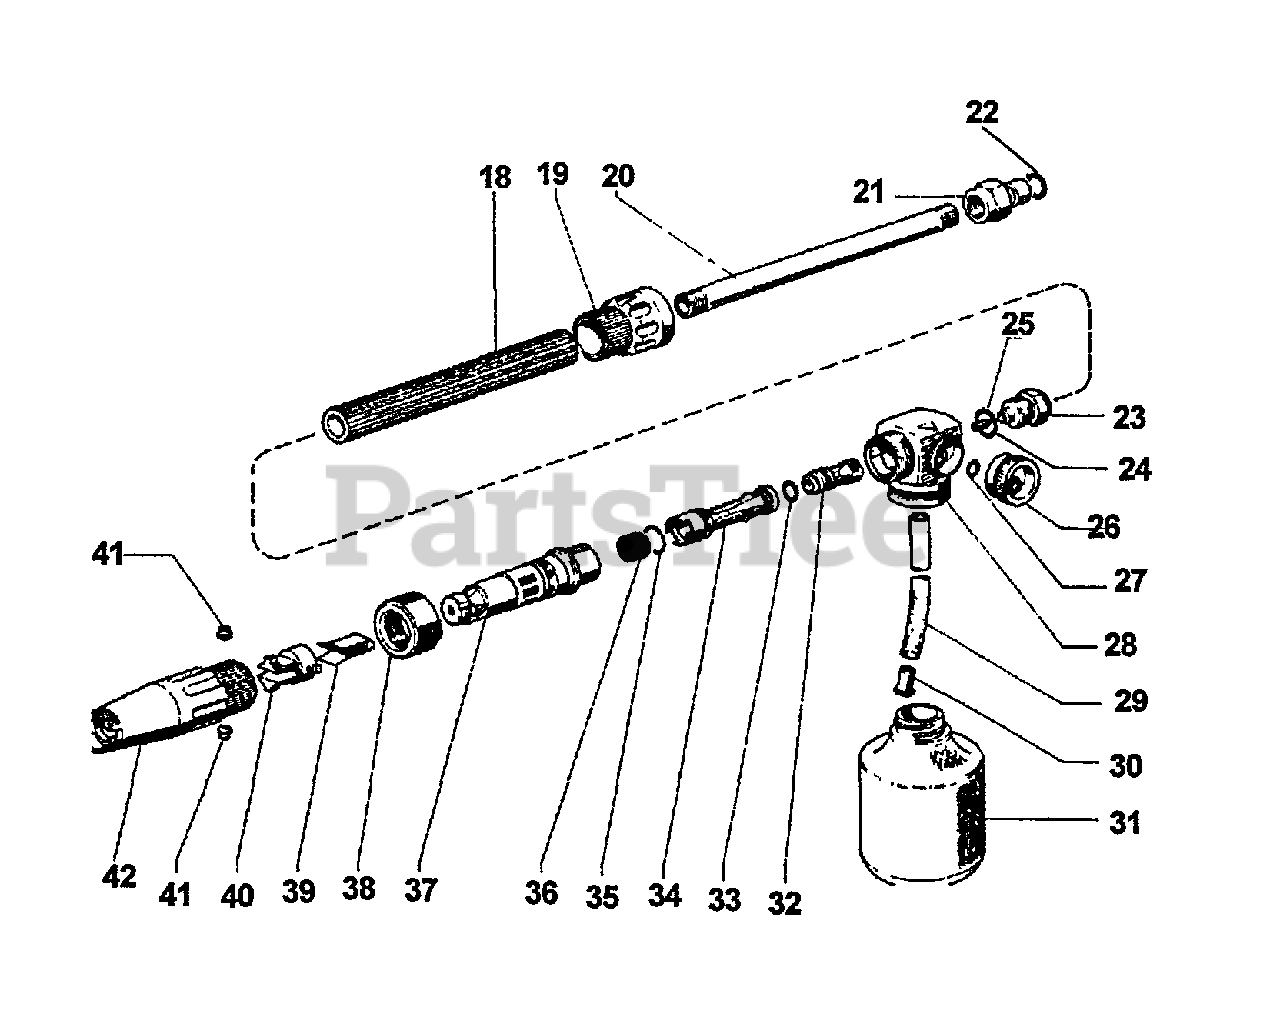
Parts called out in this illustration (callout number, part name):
18	GRIP, HANDLE
19	RINGNUT
20	TUBE
21	COUPLING - MALE
22	O-RING - .359 X .103
23	NIPPLE
24	NOZZLE - RED
25	O-RING - .614 X .070
26	KNOB, REGULATING
27	O-RING
28	BODY
29	TUBE
30	FILTER
31	CONTAINER, 5 LITER
32	TUBE
33	O-RING
34	TUBE
35	O-RING, .489 X.070
36	FILTER
37	CYLINDER
38	NUT
40	HOLDER, BLADE
41	CAP
42	KNOB, REGULATING
